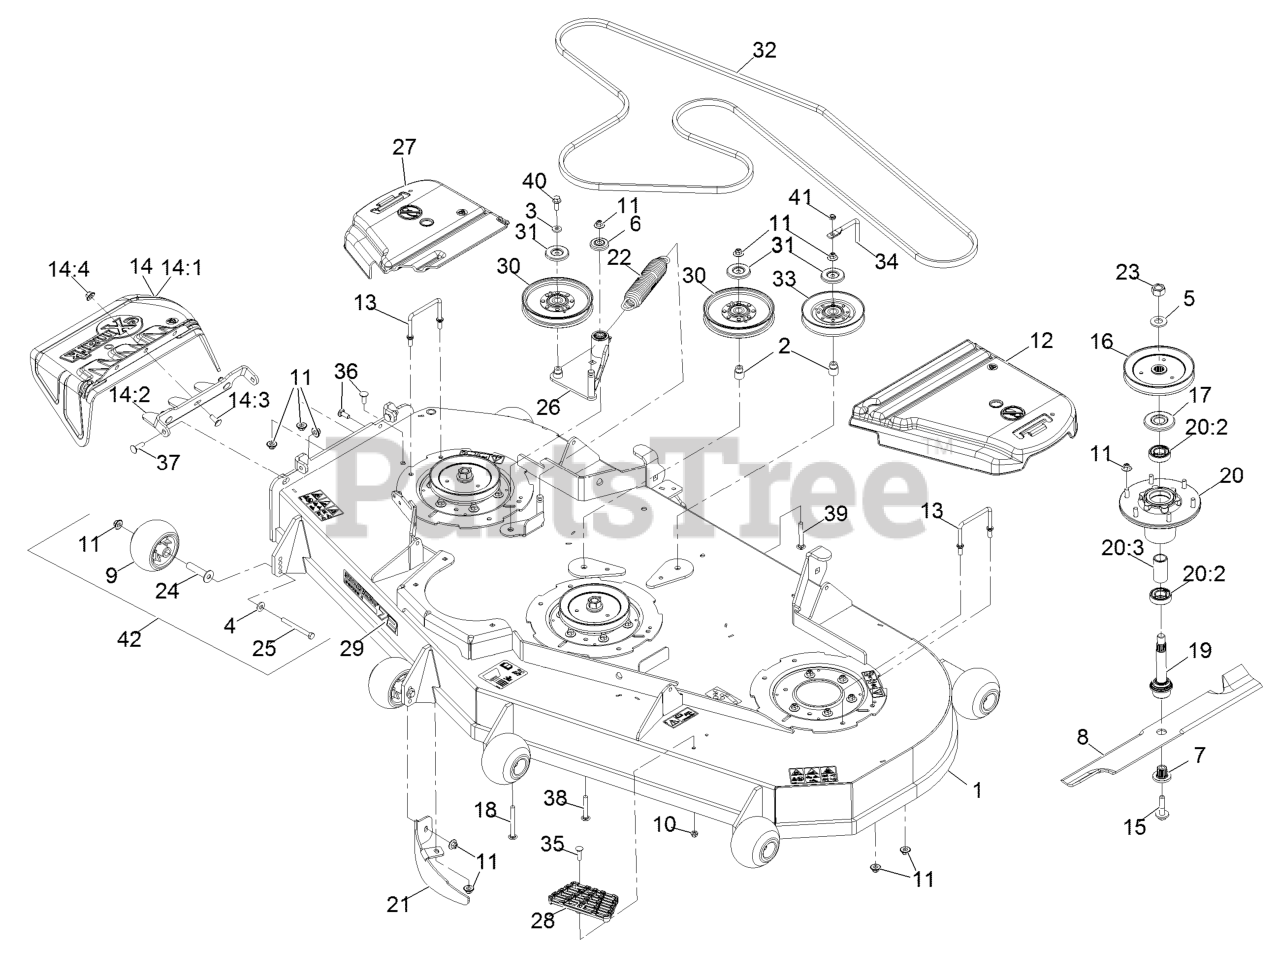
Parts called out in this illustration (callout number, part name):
1	Deck-724
2	Bushing, Idler
4	Washer-Spring Disc 3/8
5	Washer-Spring Disc 3/4
6	Guard-Top
7	Bushing, Splined
8	Blade, Low Lift (72")
8	Blade, Mulching
8	Blade, Notched (72")
8	Blade-Extreme 2, 24.50"
8	Blade, Solid (72")
9	Roller-Anti-Scalp
10	Nut-Nyloc 5/16-18 Flg
11	Nut-Nyloc 3/8-16 Flg
12	Cover-Belt, LH
13	Wireform-Cover
14	ASM,Discharge Chute
14:1	Chute, Discharge
14:2	Bracket,Discharge Chute
14:3	Bolt-Carriage 3/8-16 X 1
14:4	Nut-Nyloc 3/8-16 Flg
15	Screw-Sems 1/2-20 X 2.19
16	Sheave,Blade Drive 6.50
17	Guard,Bearing Top .989
18	Bolt-Carriage Shoulder 3/8-16 X 3 1/2
19	ASM-Spindle And Seal
20	ASM-Cutter Hsg With Bearings
20:2	Bearing-Ball
20:3	Spacer-Bearing
21	Baffle-Dogleg, Lz72
22	Spring-Extension
23	Nut-Hex
24	Axle, Roller
25	Screw-HH 3/8-16 X 3 3/4 GR 8
26	Idler Arm ASM
27	Shield-Belt
28	Step-Deck
29	Decal, 724
30	Idler-Pulley
31	Shield-Dust
33	Idler V
34	Guide-Belt
35	Bolt-Carriage 5/16-18 X 1 1/4
36	Bolt-Carriage 3/8-16 X 1
37	Bolt-Carriage 3/8-16 X 1 1/4
38	Bolt-Carriage 3/8-16 X 2 1/2
39	Bolt-Carriage 3/8-16 X 2 3/4
40	Screw-HH Flg 3/8-16 X 1
41	Nut-Nyloc 3/8-16 Thin
42	Kit, Anti-Scalp Roller
